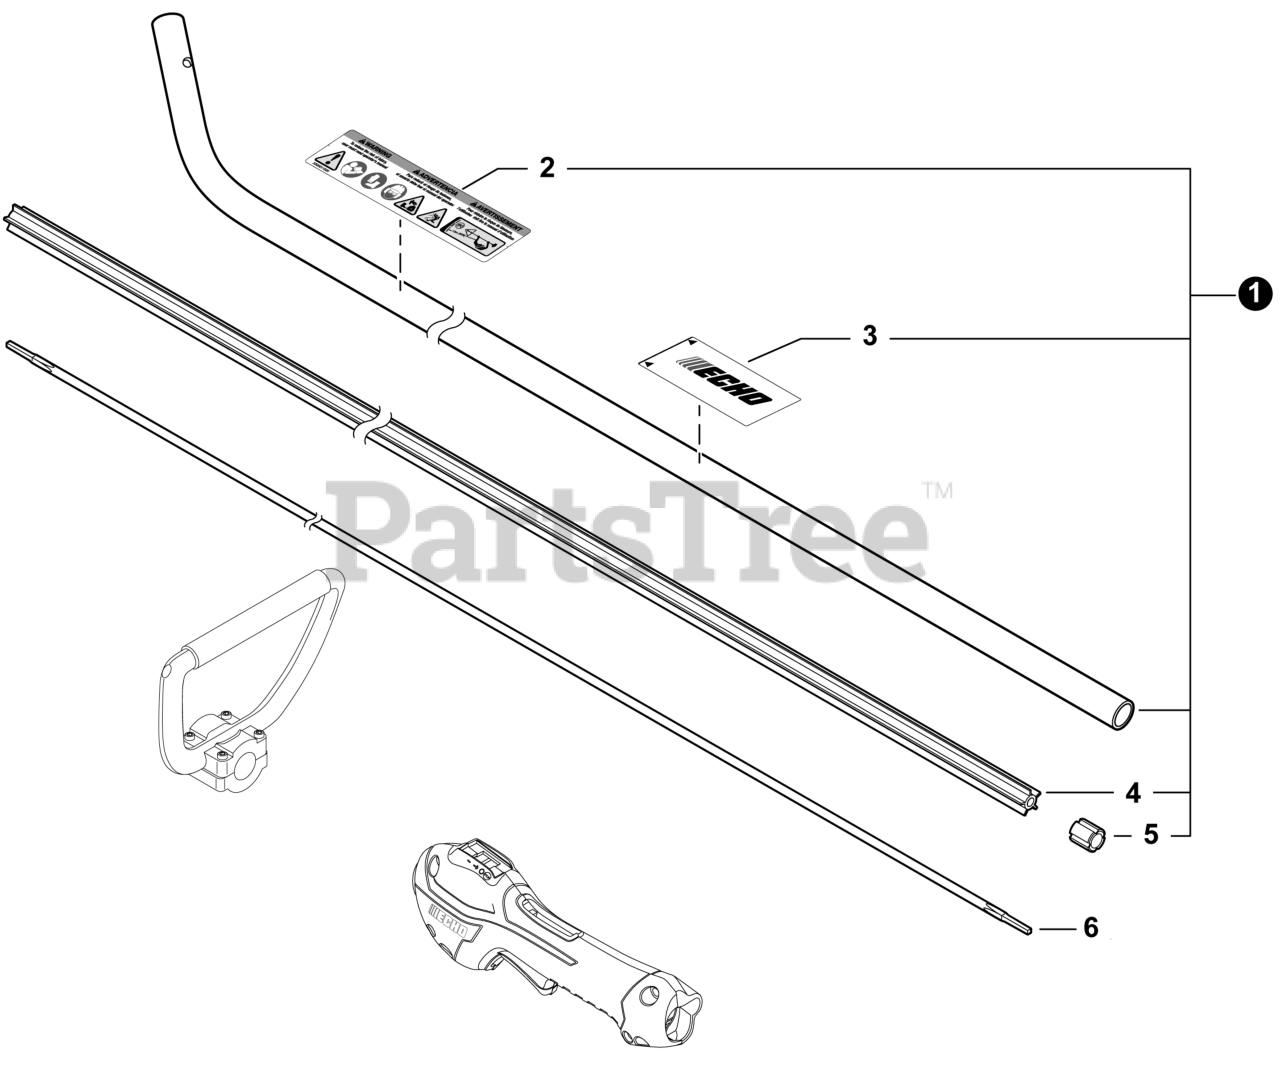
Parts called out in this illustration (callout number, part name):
1	MAIN PIPE ASSY
2	LABEL - CAUTION ISO
3	LABEL - HANDLE LOCATION
4	LINER, FLEXIBLE
5	STOPPER
6	DRIVESHAFT - FLEXIBLE
